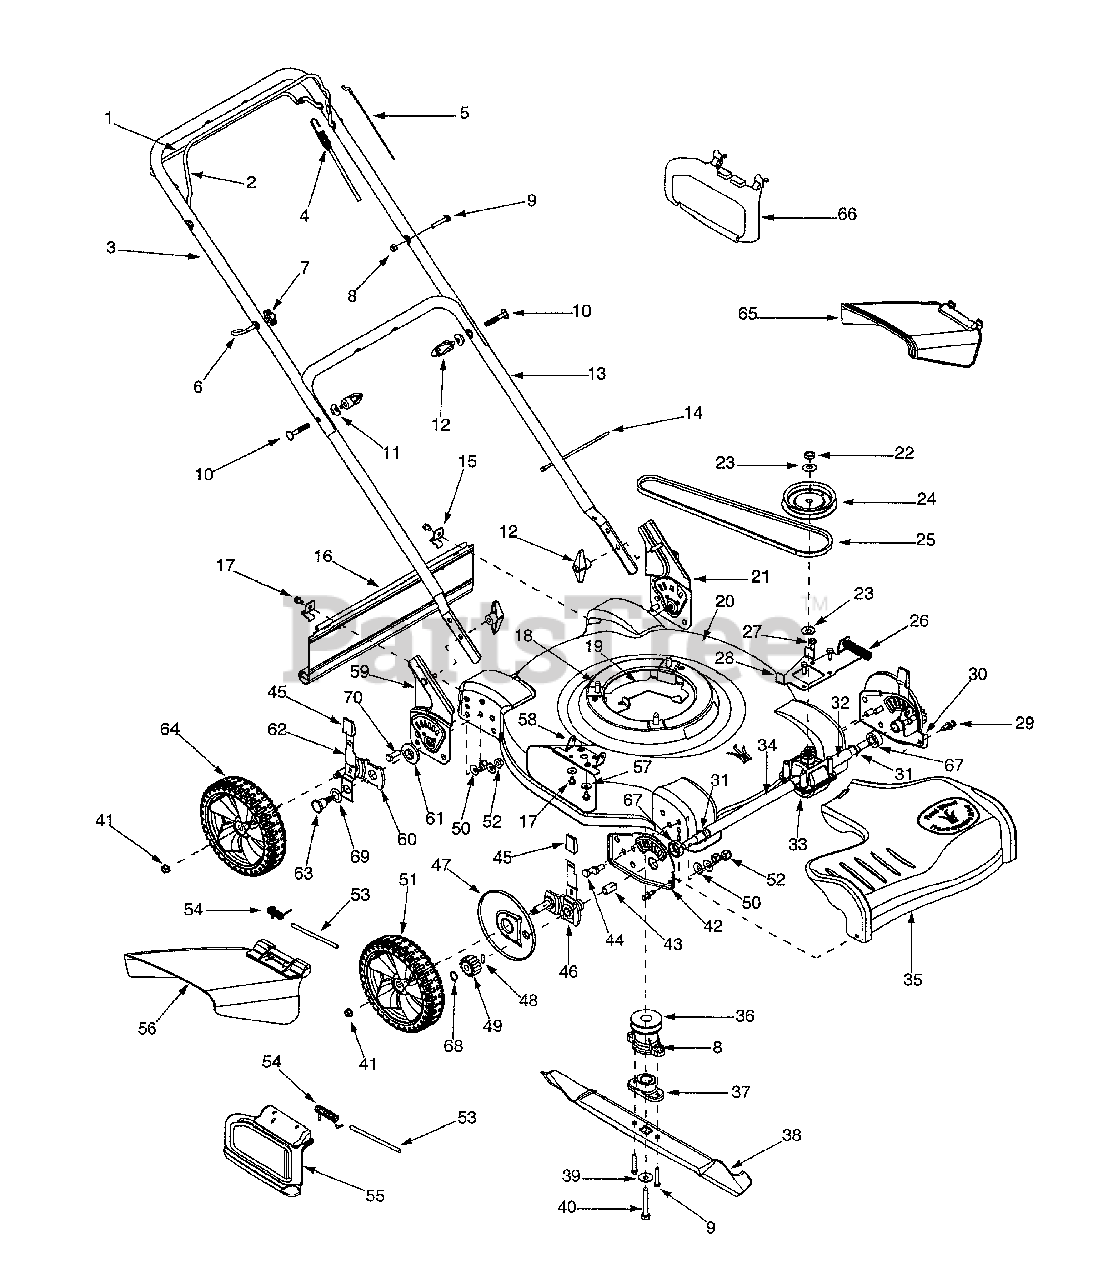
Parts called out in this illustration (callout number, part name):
1	Drive Control Handle
4	Drive Control Cable
5	Blade Control Cable - B&S
5	Blade Control Cable- Tec
6	Eye Bolt
7	Wing Nut 1/4-20
8	Hex Lock Nut 1/4-20
9	Hex Cap Screw 1 /4-20x 1.5
10	Carriage Bolt 5/16-18 x 2.0
11	Shoulder Washer .320 ID x .93 OD
12	Wing Nut 5/16-18
14	Cable Tie
15	Hinge Clip
16	Trail Shield
17	Hex Screw 1/4-14 x .625
18	Hex Washer Screw 3/8-16 x 1.0
19	Engine Belt Keeper Bracket
22	Jam Nut 7/16-20
23	Bell Washer .45 ID x 1.00 OD
24	Pulley
25	V-Belt
26	Compression Spring
27	Hex Washer Screw 1/4-20 x .500
28	Transmission Belt Keeper Bracket
29	Rivet
31	Retainer Ring
32	Sleeve Spacer .550 ID x 2.5
33	Transmission Assembly
34	Sleeve Spacer .550 ID x 8.9
35	Transmission Cover
36	Drive Pulley
37	Blade Adapter
38	Blade 22"
38	Mulching Blade 22"
39	Bell Washer .396 ID x 1.140 OD
40	Hex Cap Screw 3/8-24 x 1.5
41	Lock Nut 3/8-16
43	Sleeve Bearing
44	Hex Cap Screw 3/8-16 x .75
45	Adjustment Knob
46	Spring Lever Assembly - LH* On FWD
46	Spring Lever Assembly - RH* On FWD
47	Wheel Dust Cover
48	Pin
49	Spur Gear 14T - LH
49	Spur Gear 14T- RH
50	Washer Spacer .401 ID x .870 OD
51	Front Wheel Assembly 8 x 1.8
52	Hex Lock Nut 3/8-16
53	Hinge Pin
54	Torsion Spring
55	Mulching Baffle
56	Side Discharge Assembly
57	Bell Washer .265 ID x .75 OD
58	Chute Hinge
61	Height Adjustment Bearing
62	Spring Lever
63	Shoulder Screw 3/8-16
64	Rear Wheel 8 x 1.8
65	Snap Discharge Chute
66	Snap Mulching Plug
67	Bearing Spacer
68	Snap Ring .500
69	Bell Washer .760 ID x 1.25 OD
70	Hex Cap Screw 3/8-16 x 1.0
